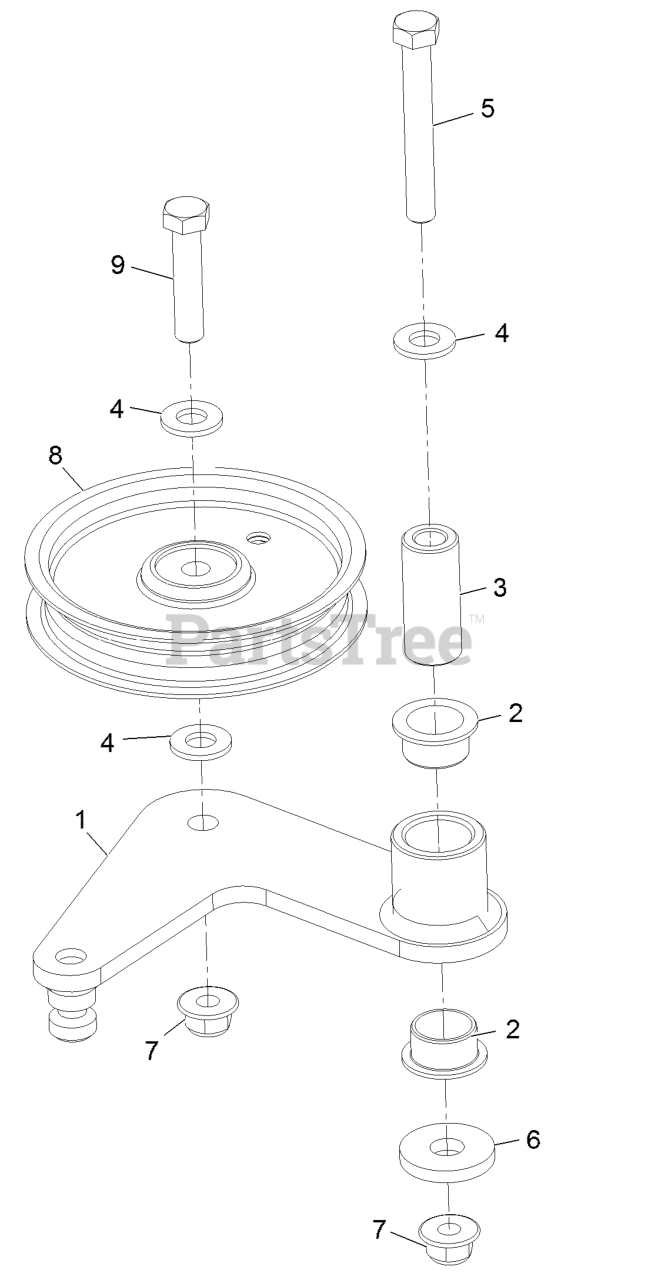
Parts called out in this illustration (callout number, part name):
1	Idler Arm ASM
2	Bushing-Flanged
3	Spacer, Pivot
4	Washer-3/8 SAE
5	Screw-HH 3/8-16 X 2 3/4
7	Nut-Nyloc 3/8-16 Flg
8	Pulley-Idler
9	Screw-HH 3/8-16 X 1 3/4
